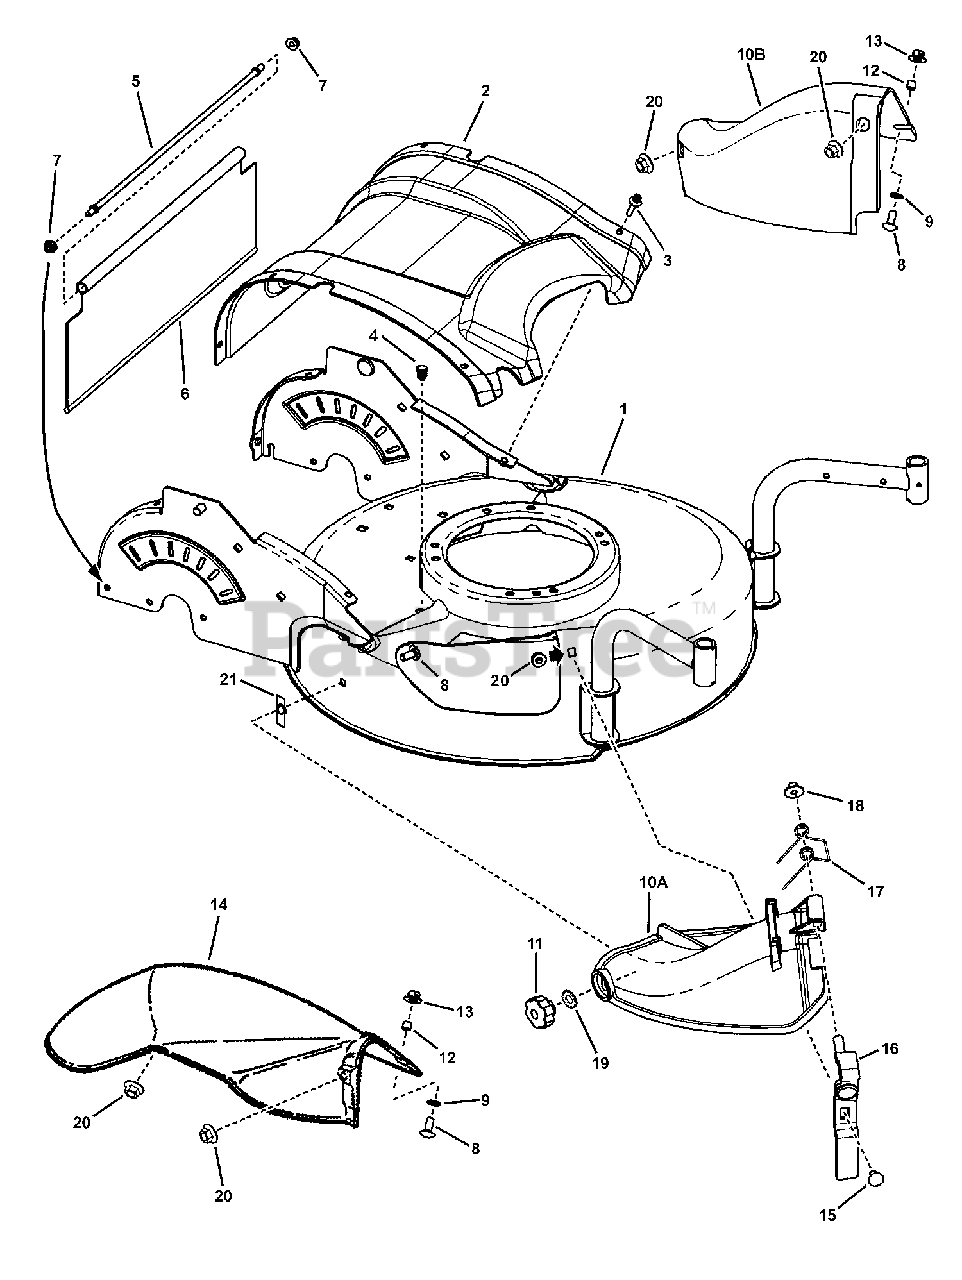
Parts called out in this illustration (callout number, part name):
1	WELDMENT, 21" Deck Swivel Wheel
2	REAR COVER, Belt/Transmission
3	RIVET, Plastic, Fastener
4	PLUG, Hole (Polyethylene)
5	ROD, Trail Shield
6	SHIELD, Trail
7	NUT, 1/4-20 Hex Flange Lock
8	BOLT, 5/16-18 x 3/4" Short Square Neck Carriage, GR 5
9	BOLT RETAINER, 5/16- Black
10A	COVER, Mulching, No Tools
10B	COVER, 21 Deck Recycling
11	KNOB, Fluted (5/16-18 thread)
12	SPACER, .316 x .375 x .300/.310
13	NUT, 5/16-18 Large Flange Hex Center Lock
14	CHUTE, 21 Side Discharge
15	BOLT, 5/16-18 x 5/8" Short Square Neck Carriage, GR5
16	WELDMENT, Hinge Pivot
17	SPRING, Torsion, Mulching Cover
18	PUSHNUT, 3/8"
19	WASHER, 5/16" Internal/External
20	NUT, 5/16-18 Hex Flange Lock
21	NUT, 5/16-18 Speed
